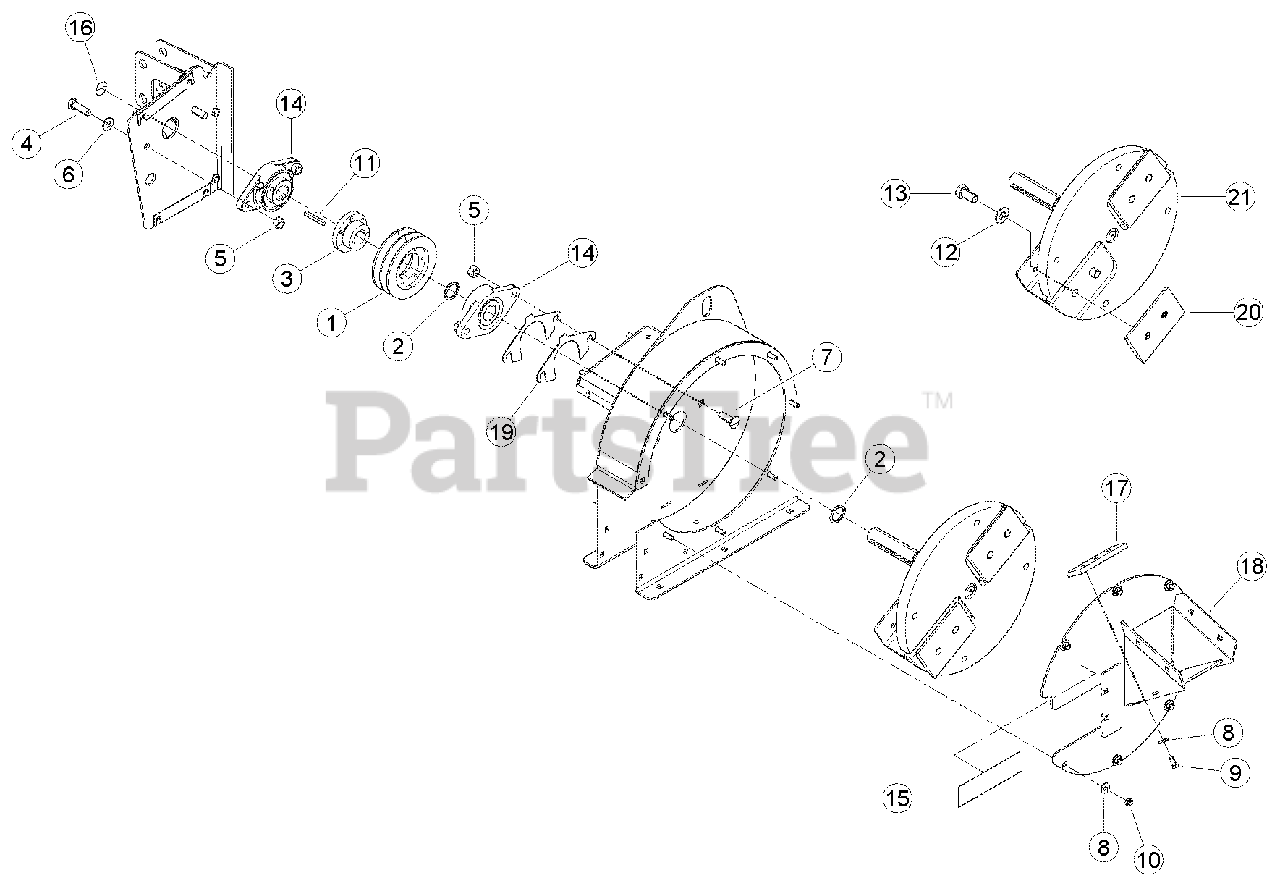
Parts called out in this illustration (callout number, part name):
1	SHEAVE, 2B4.8 SDS
2	SNAP RING, 1-1/4 EXT. HEAVY DUTY
3	BUSHING, SDS 1-1/4"
4	BOLT, 1/2 X 1-1/2 HEX HD GR5 ZP
5	NUT, 1/2 CENTERLOCK GRB ZP
6	WASHER, 1/2 SAE FLAT ZP
7	BOLT, 1/2 X 1-1/2 CRG GR5 ZP
8	WASHER, 5/16 FLAT ZP
9	BOLT, 5/16 X 5/8 HEX HD GR5 ZP
10	NUT, 5/16 NE NYLOCK ZP
11	KEY, 1/4 SQUARE X 2 LONG PLAIN
12	WASHER, 5/8 SAE HARDENED
13	BOLT, M16 X 2.0 X 30 HEX HD W/PATCH
14	BEARING, 1-1/4" DIA 2 BOLT FLANGE
15	DECAL, ECHO BEARCAT 6.82 X 1.90
16	DECAL, ROTATING SHAFT
17	ANVIL, CHIPPER
18	WELDMENT, DISK COVER
19	SHIM, BEARING
20	BLADE, BIG CHIPPER (REPLACED AND SUPERSEDED. FOR SERVICE ORDERKIT #76295-00, REPLACEMENT BLADE)
20	KIT, 4-1/2 CHIPPER BLADE KIT
21	WELDMENT, 4-1/2 PTO DISK
